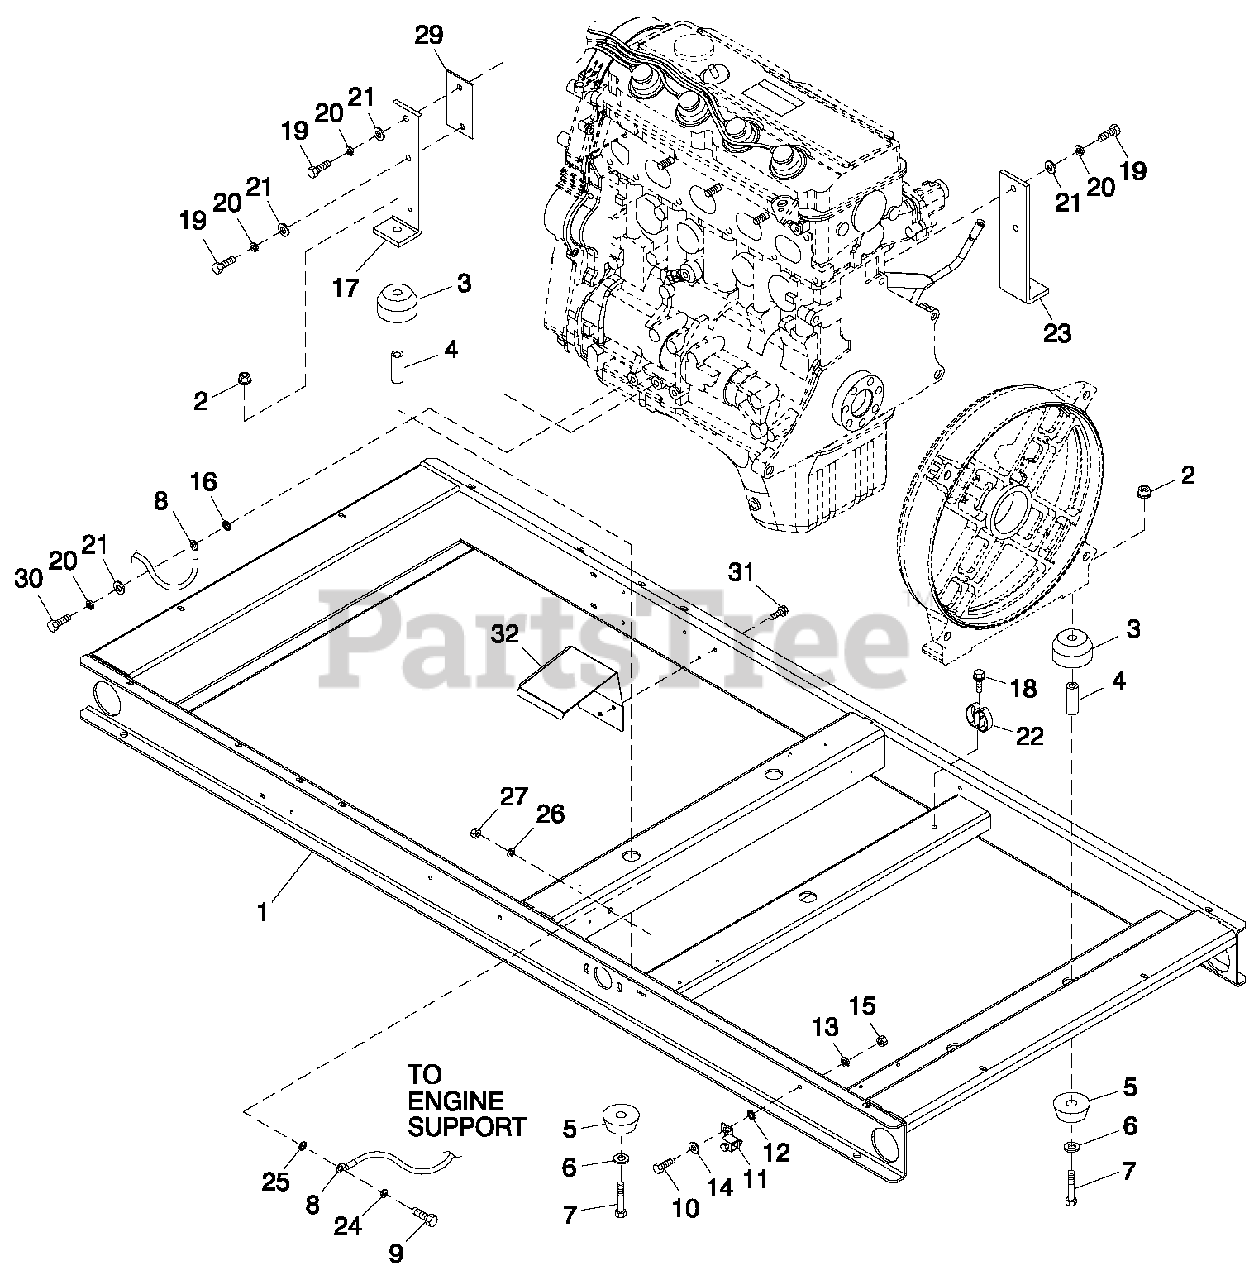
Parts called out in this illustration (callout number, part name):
1	ROTOR-2390-45KD1 CPL
2	ROTOR-2390-35KD1 CPL
3	ROTOR-2390-45KD1 CPL (G2)
4	ROTOR-2390-35KD1 CPL (G2)
5	ROTOR 25KW 3PH DIRECT 390 1800
6	ROTOR 25KW 1PH DIRECT 390 1800
7	SCREW HHC M12-1.75 X 80 G8.8
8	ASSY WIRE 14.00"
9	SCREW HHC M8-1.25X 30 G8.8
10	STATOR-390 45K 2P 1PH DIRECT
11	STATOR-2390-35AD1 CPL
12	STATOR-2390-35KD1 CPL
13	STATOR-2390-35GD1 CPL
14	STATOR-2309-45KW 2P 3PH 208V
15	STATOR-2309-45-KD1 CPL
16	WASHER SHAKEPROOF INT 3/8
17	SUPPORT LH ENGINE 2.4L
18	SCREW HHTT M4-0.7X8BP
19	SCREW HHC M10-1.25 X 30 G8.8
20	WASHER LOCK 7/16
21	WASHER FLAT 3/8-M10 ZINC
22	SPRING CLIP HOLDER .37-.62
23	SUPPORT RH ENGINE 2.4L
24	WASHER LOCK M8-5/16
25	WASHER LOCK SPECIAL 5/16
26	WASHER FLAT 5/16-M8 ZINC
27	NUT HEX M8-1.25 G8 CLEAR ZINC
29	SPACER ENGINE MOUNT (2.4L G1)
30	SCREW HHC M10-1.25 X 25 C8.8
31	SCREW HWHT M6-1 X 16 N WA Z/JS
32	HEAT SHIELD 2.4L G2
